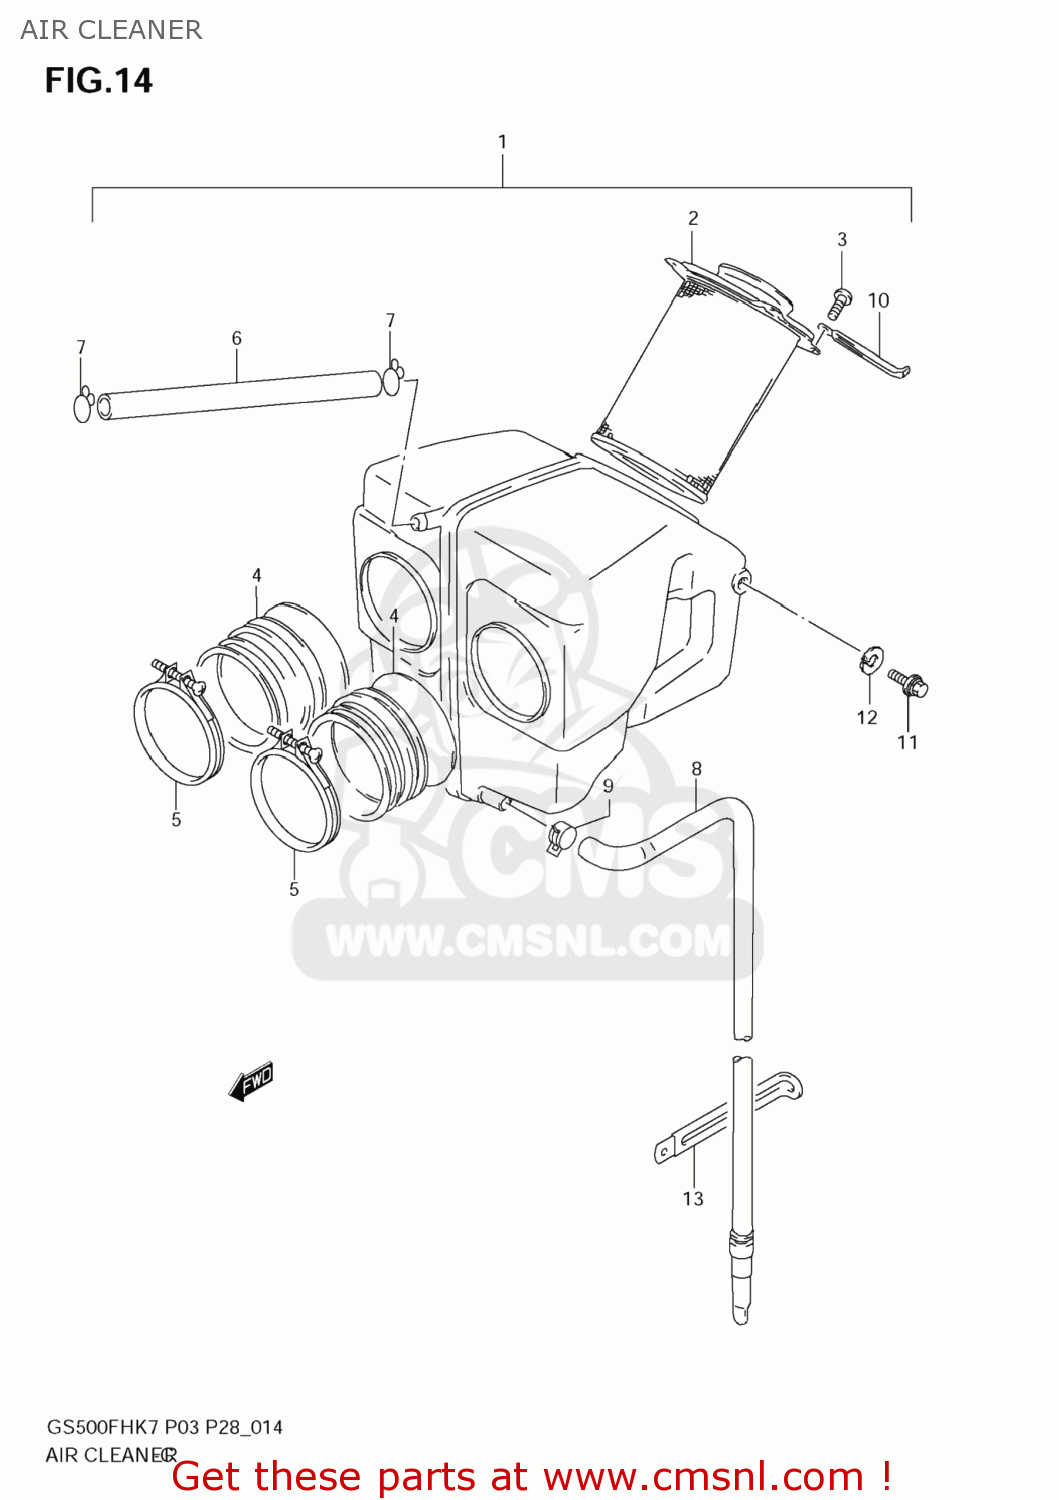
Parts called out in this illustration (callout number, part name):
1	CLEANER ASSY,AIR
2	FILTER ASSY
3	SCREW
4	TUBE,OUTLET
5	CLAMP
6	HOSE(11X15X600)
7	CLIP
8	TUBE,DRAIN
9	CLIP
10	CLAMP(L:65)
11	BOLT UH125&200
12	WASHER
13	CLAMP(L:80)
